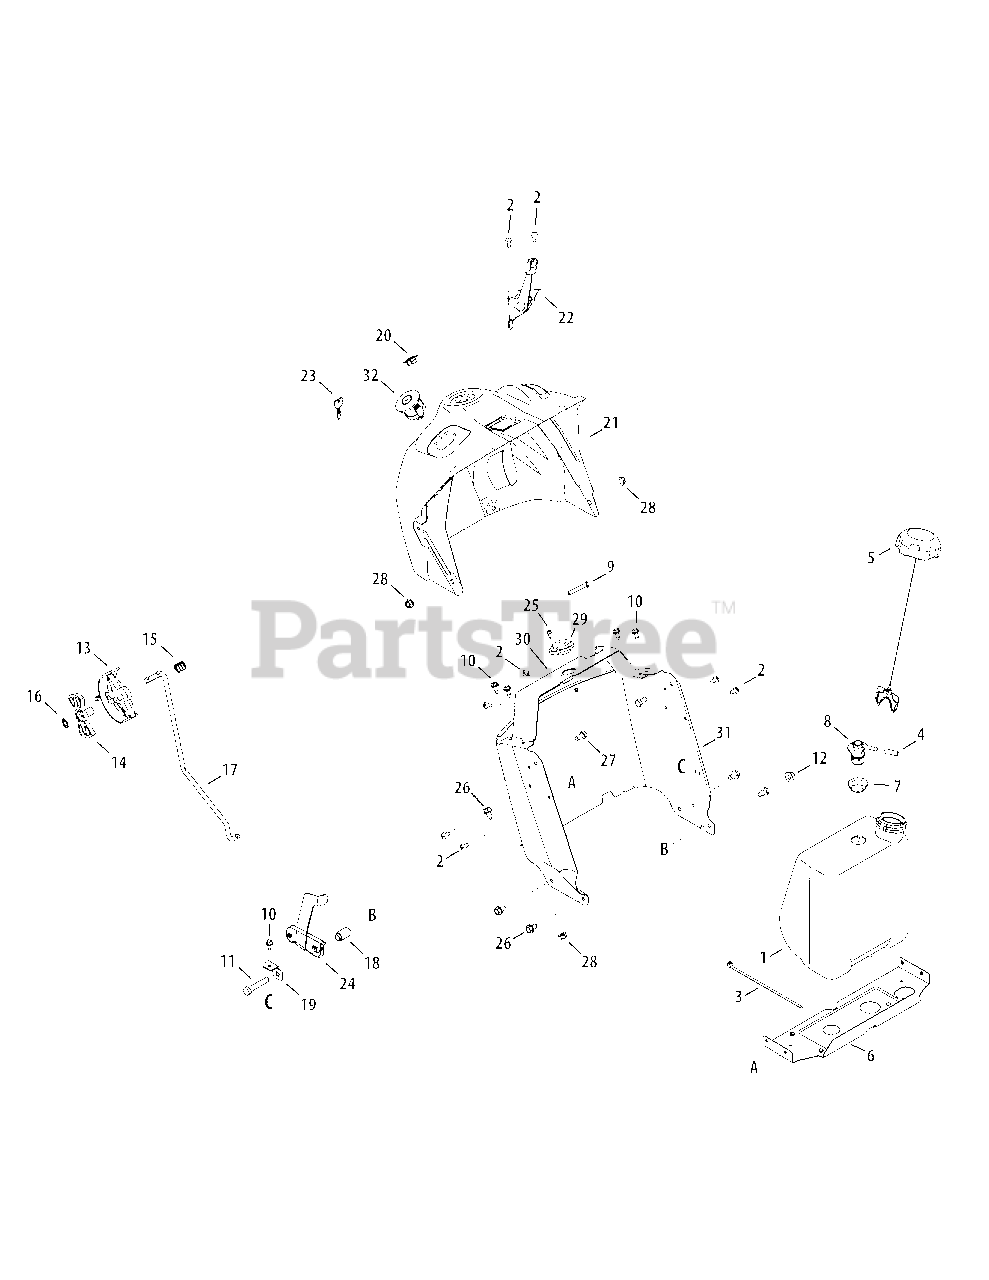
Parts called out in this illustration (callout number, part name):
1	Fuel Tank
2	Screw, Tap, 1/4-20x 0.500
3	Cable Tie, 36.0 Long
4	Hose Vent
5	Fuel Cap
6	Gas Tank Support Bracket
7	Rubber Grommet, 23 x 3.55
8	Rollover Valve
9	Hex Screw, 1/4-20 x 1.50
10	Tap Screw, 1/4-20x0.625
11	Hex Screw, 3/8-16x2.00, Gr5, Std
12	Flange Lock Nut, 3/8-16
13	Shift Lever
14	Index Control
15	Compr Spring, .685 OD x .63
16	Lock Washer, 1/4
17	Speed Selector Control Rod
18	Flange Spacer, .390 X .671 X 1.095
19	Speed Latch
20	Choke Plug
21	Dash, Upper
22	Throttle/Choke Cable Assembly
24	Speed Latch - No RMC
25	Screw, #10-16 x .500
26	Tap Screw,5/16-18, 0.625
27	Hex Screw, 5/16-18 x .625
28	Flange Lock Nut, 5/16-18
29	Bearing, .628 ID x 1.36
30	Bracket, Steering Support
31	Dash, Lower
32	Key Switch
